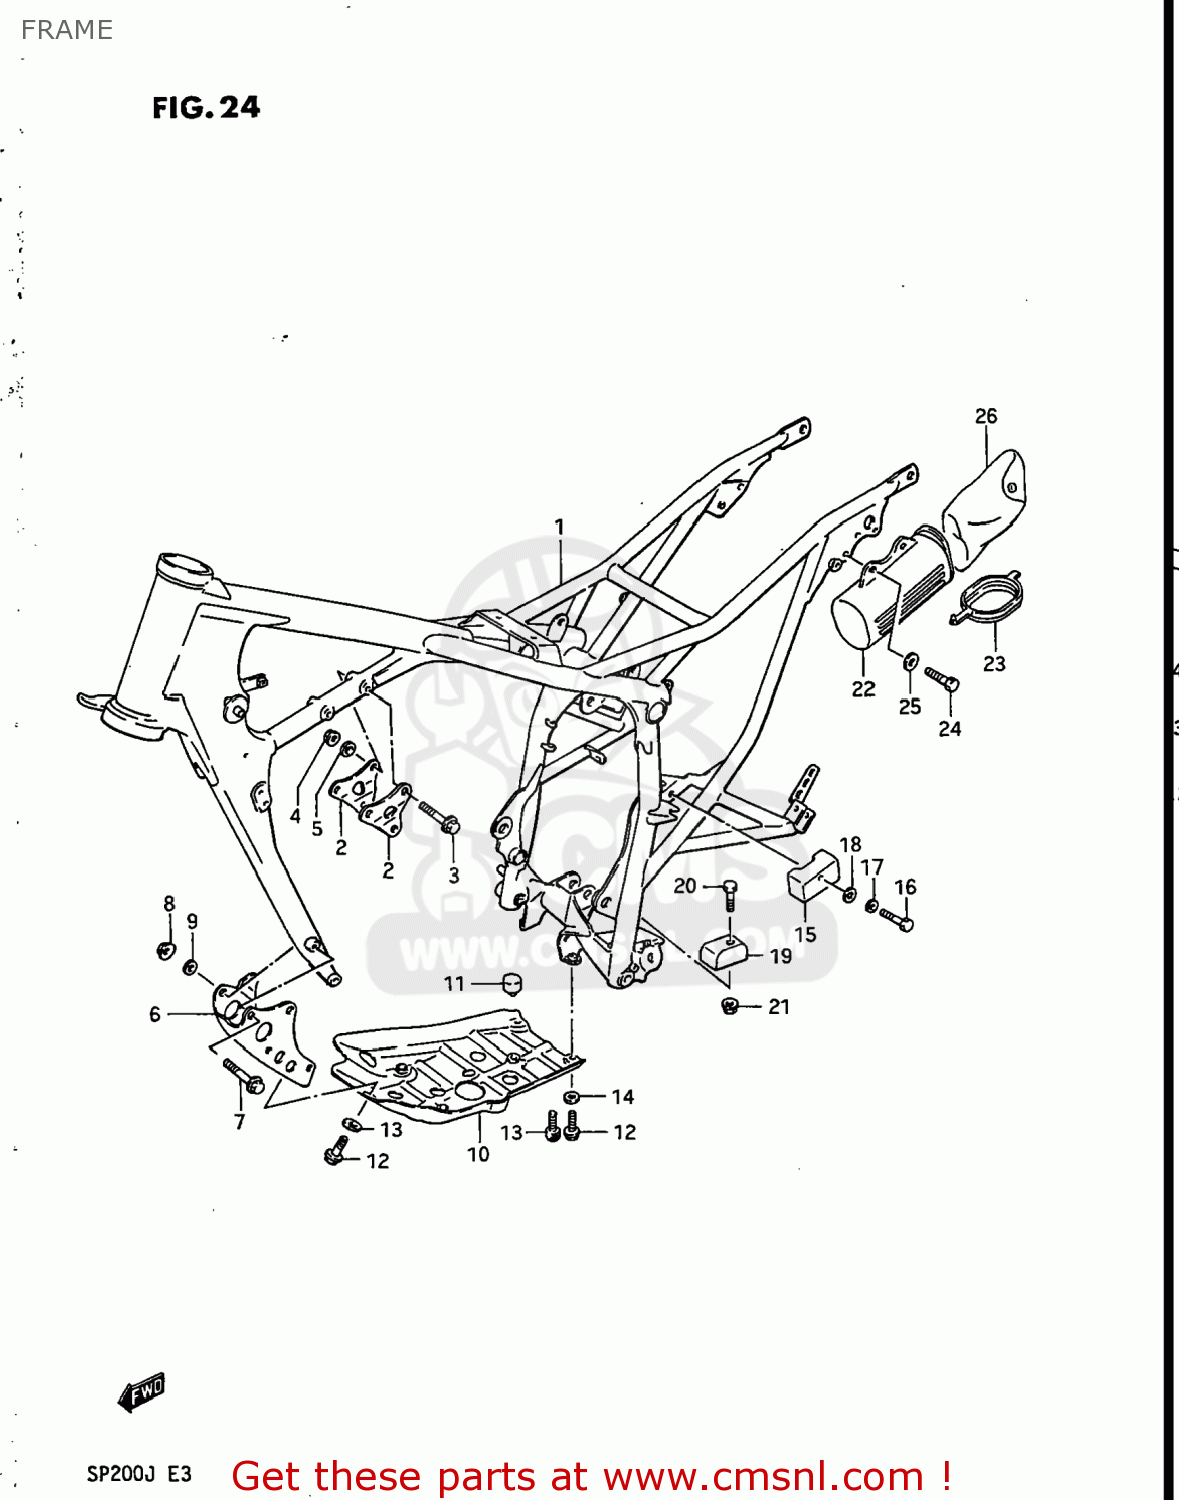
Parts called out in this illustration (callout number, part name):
1	FRAME
2	PLATE,ENGINE MOUNT UPR
3	BOLT
4	NUT
5	LOCK WASHER
6	PLATE,ENGINE MOUNT LWR
7	BOLT 8X70
8	NUT
9	LOCK WASHER
10	PROTECTOR,ENGINE
11	CUSHION
12	BOLT 6X12
13	BOLT
14	WASHER
15	GUIDE,CHAIN
16	BOLT 6X35
17	WASHER,LOCK
18	WASHER
19	GUIDE,CH LENGTH CONTROL LWR
20	BOLT
21	NUT 6MM
22	HOLDER,TOOL
23	CAP,HOLDER
24	BOLT 6X16
25	WASHER (6.5X18X1.6)
26	TOOL SET
